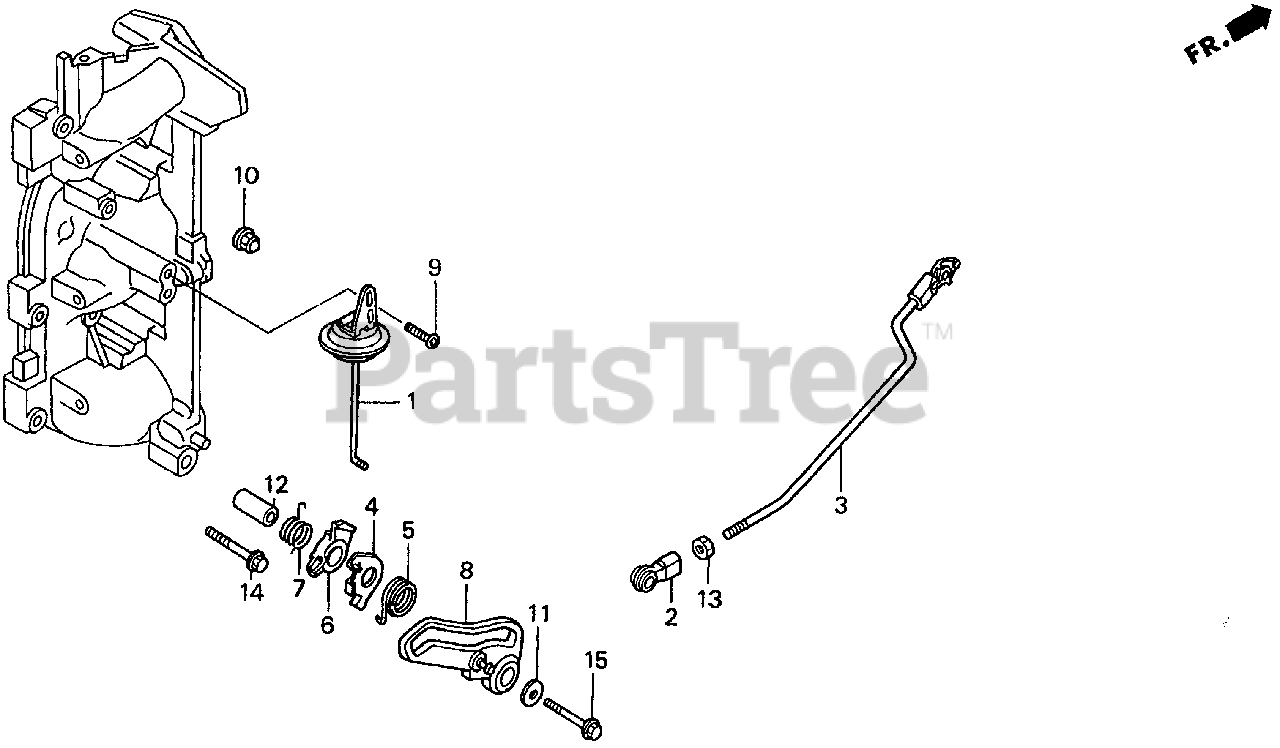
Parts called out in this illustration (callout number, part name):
1	DIAPHRAGM ASSY.
2	LINKAGE, PIVOT
3	ROD, THROTTLE
4	PLATE, ASSIST
5	SPRING, ASSIST
6	CAM, THROTTLE OPENER
7	SPRING, OPENER CAM RETURN
8	CAM, THROTTLE
9	BOLT, TORX (6X14)
10	NUT, CAP (6MM)
11	WASHER, PLAIN (6MM)
12	COLLAR (6.7X12.5X24)
13	NUT, HEX. (5MM)
14	BOLT, FLANGE (6X32)
15	BOLT, FLANGE (6X40)
